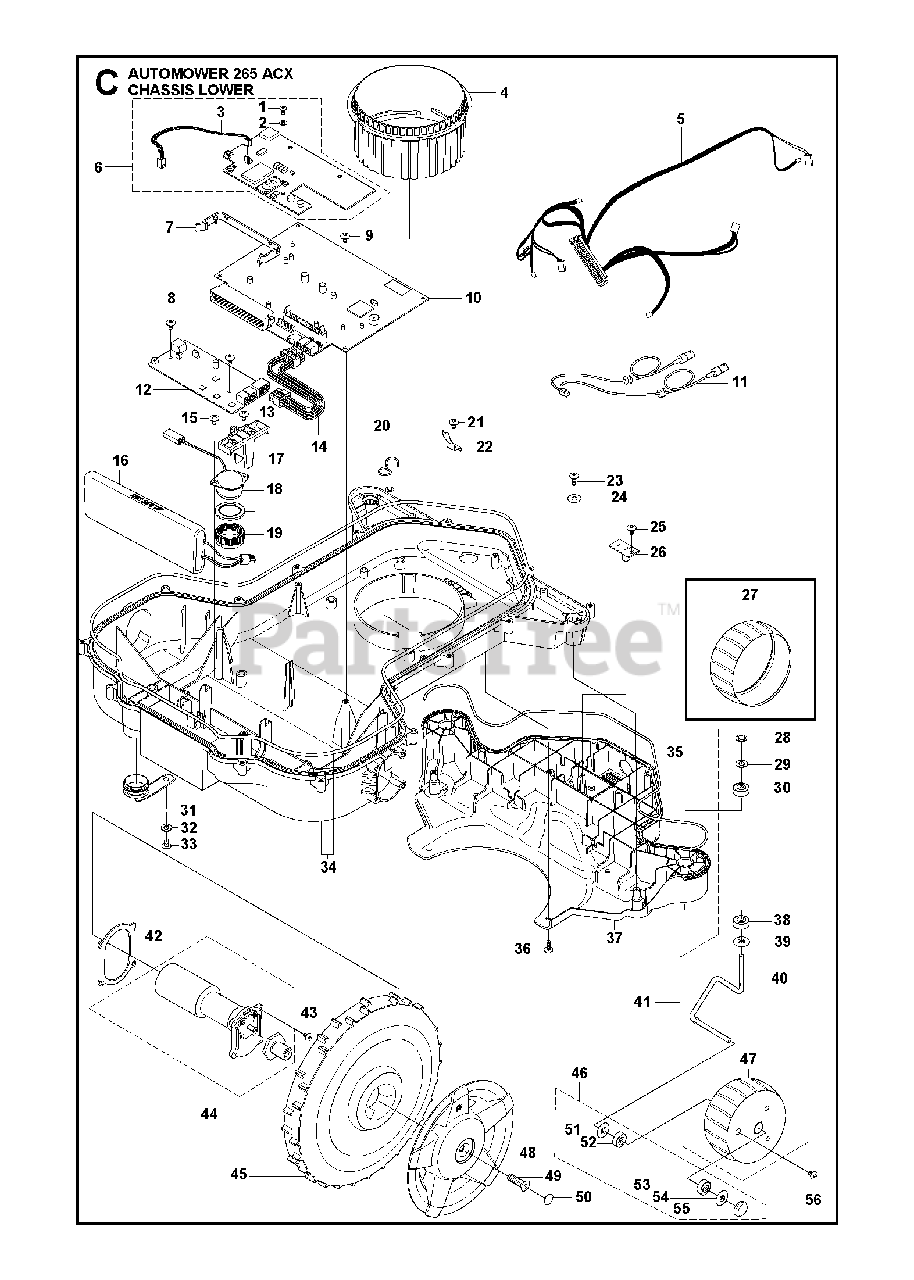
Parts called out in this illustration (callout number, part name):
1	SCREW GSM- MODULE
2	WASHER GSM- MODULE
3	LOOM LOOM GPS TRACKING MODULE
4	CUTTING HEIGHT NUT
7	CLIP MAIN CONNECTOR
7	CLIP MAIN CONNECTOR 50PCS
8	SCREW 12MM
9	SCREW SILVER 10MM
13	SCREW 14MM
15	SCREW
19	NUT BUZZER
23	SCREW 14MM
25	SCREW SILVER 10MM
26	PRINTED CIRCUIT ASSY
27	WHEEL RUBBER TYRE
28	LOCK WASHER PUSH-ON TYPE P 8 S
29	WASHER 16 OD X 6.5 ID
30	BALL BEARING FRONT WH
31	PLUG SERVICE PLUG
33	SCREW 14MM
36	SCREW 14MM
38	BALL BEARING FRONT WH
39	WASHER FRONT WHEEL CE
42	Gasket
43	SCREW
44	DRIVE MOTOR
45	REAR WHEEL
46	KIT FRONT WHEEL BEARING KIT -
47	WHEEL, FRONT
48	HUB CAP
49	SCREW
50	COVER WASHER
51	WASHER FRONT WHEEL CE
52	BALL BEARING FRONT WH
53	BALL BEARING FRONT WH
54	WASHER FRONT WHEEL CE
55	COVER WASHER FRONT WHEEL AXEL
56	SCREW ITXPANT PT 40 THREAD
